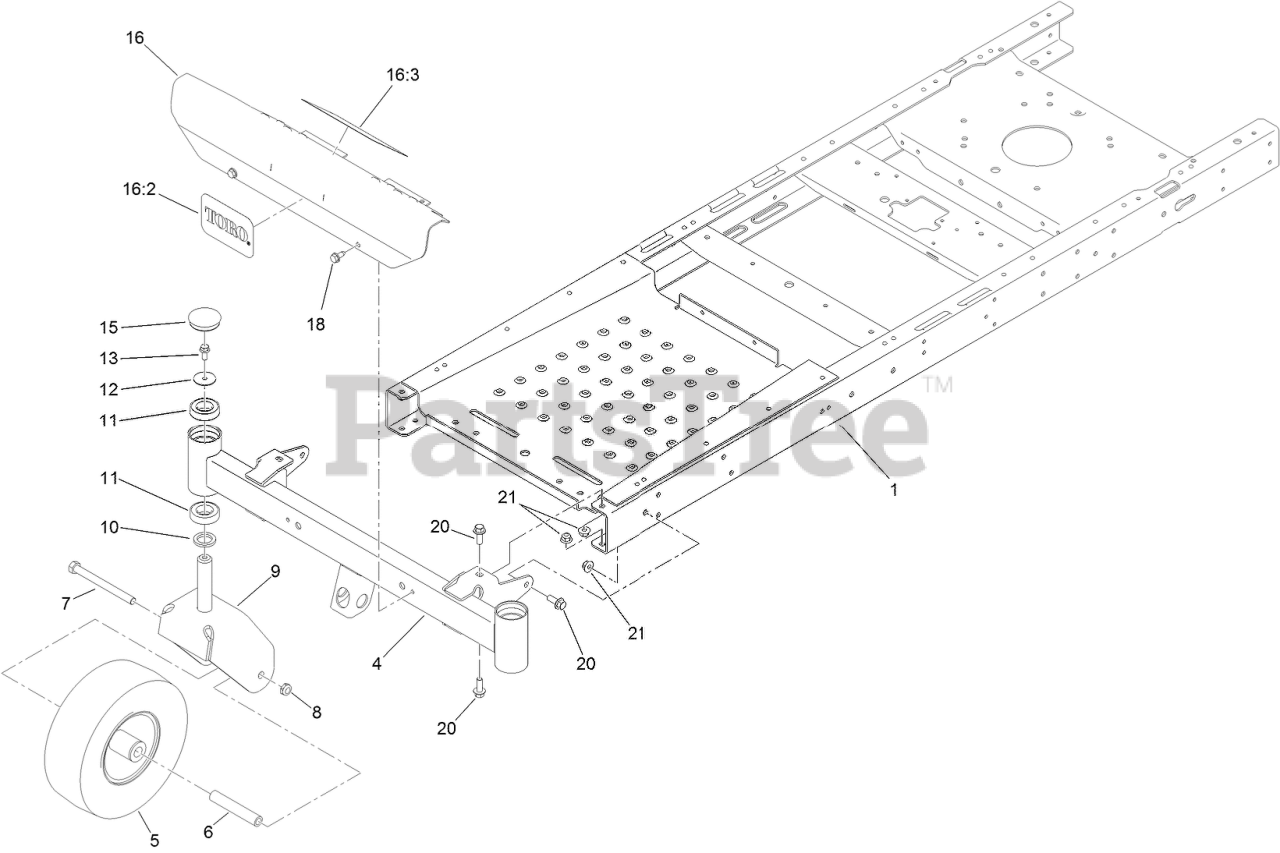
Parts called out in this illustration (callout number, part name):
1	FRAME ASM
4	AXLE-FRONT, NARROW
5	Caster Wheel ASM
6	BUSHING-SPANNER
7	SCREW-HH
8	NUT-LOCK, NI
9	FORK-CASTER
10	WASHER-THRUST
11	BEARING-BALL
12	WASHER-FLAT
13	SCREW-HHF
15	CAP-GREASE
16	FOOTREST ASM
16:3	DECAL-DANGER
18	SCREW-HWHTF
20	SCREW-HHF
21	NUT-HF, NI
